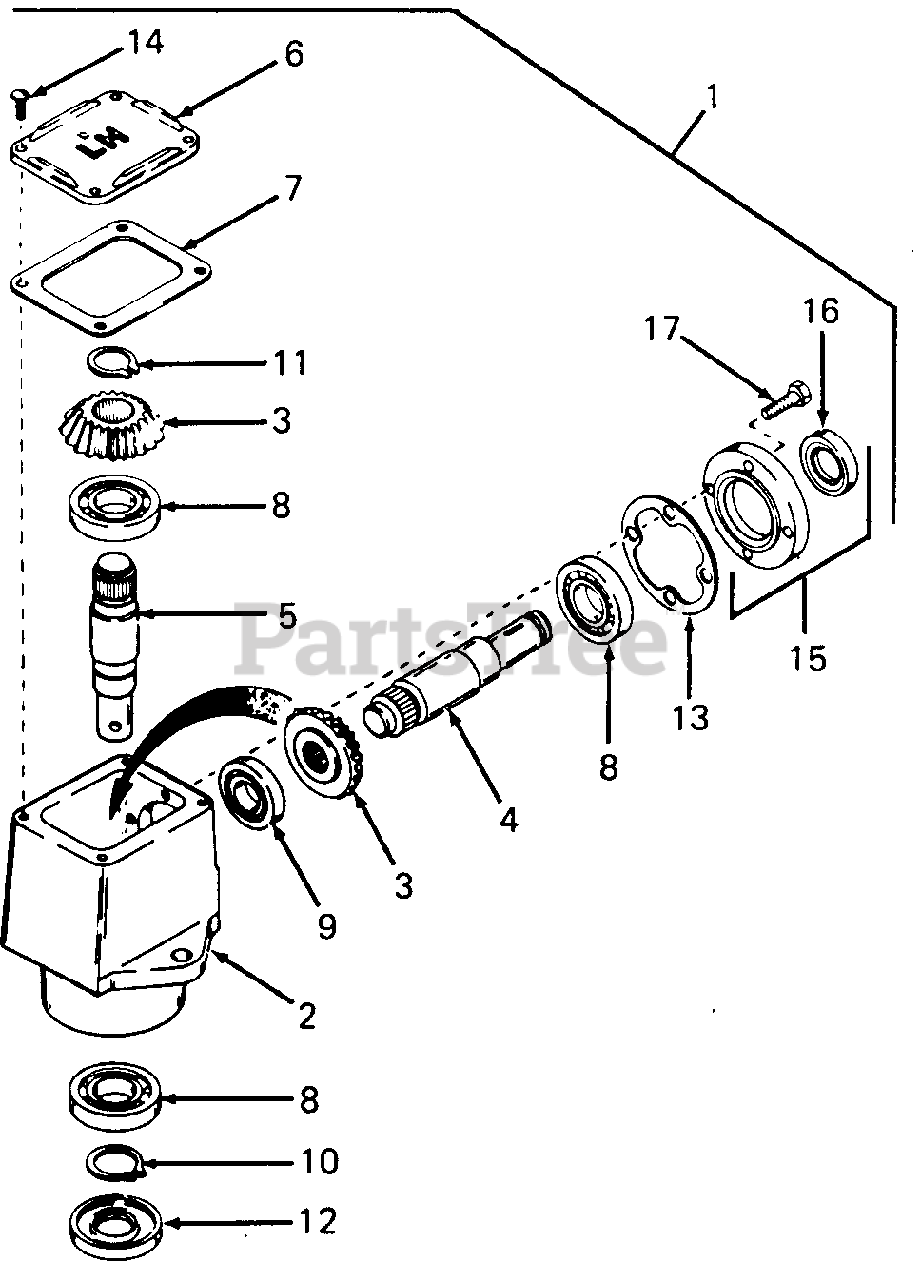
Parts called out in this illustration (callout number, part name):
1	Drive Assy, Right Angle
2	Housing, Right Angle Drive
3	Gear, Miter
4	Shaft, Input
5	Shaft, Output
7	Gasket, Cover
8	Bearing, Ball
9	Bearing, Ball
10	Ring, Snap
11	Ring, Snap
12	Seal, Oil
13	Gasket, Cap
14	Screw, Rd Hd Tap, 1/4-20 X 1/2
15	Cap & Seal Assy, Retainer
17	Screw, Hex Hd, 1/4-20 X 7/8 Lg
